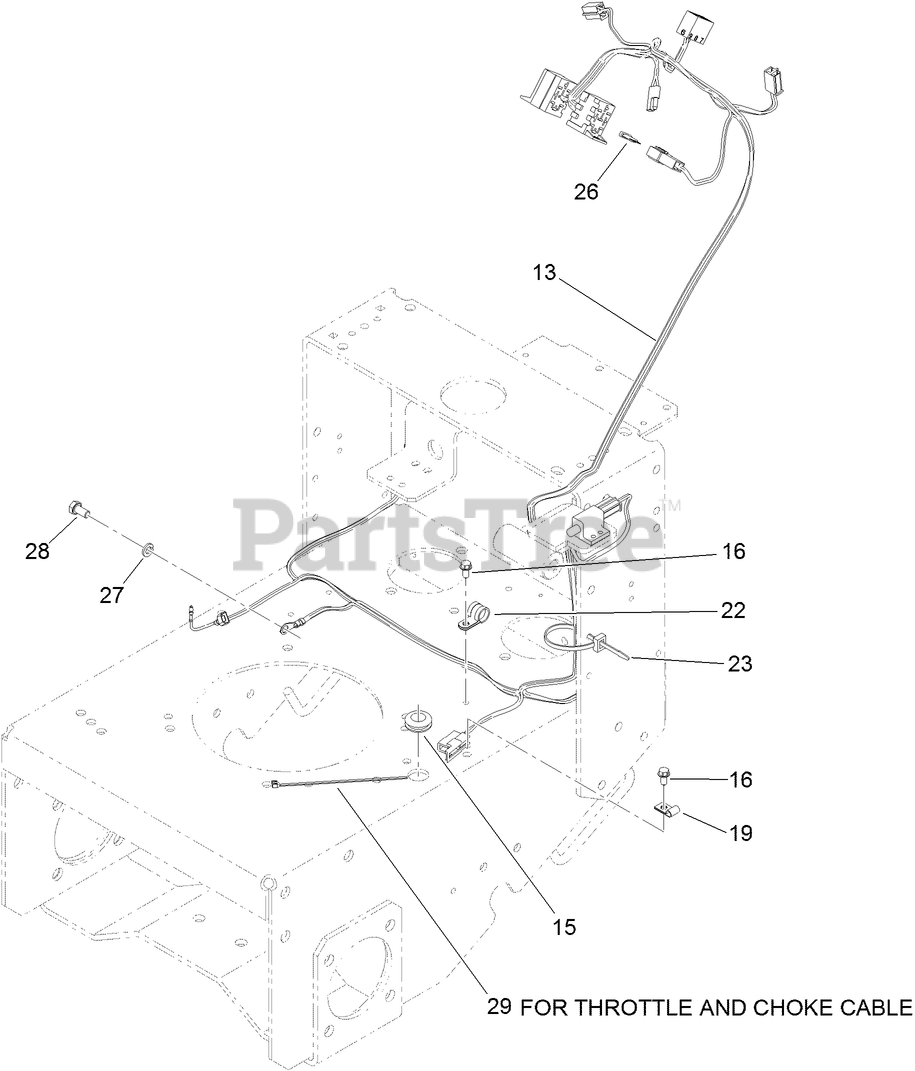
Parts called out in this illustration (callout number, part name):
13	HARNESS-WIRE
15	GROMMET
16	SCREW-HWH
19	CLIP-CLOSED, INSULATED
22	CLAMP-R
23	TIE-CABLE
26	FUSE-BLADE, 10 AMP
27	WASHER-LOCK
28	SCREW-HH
29	TIE-CABLE
